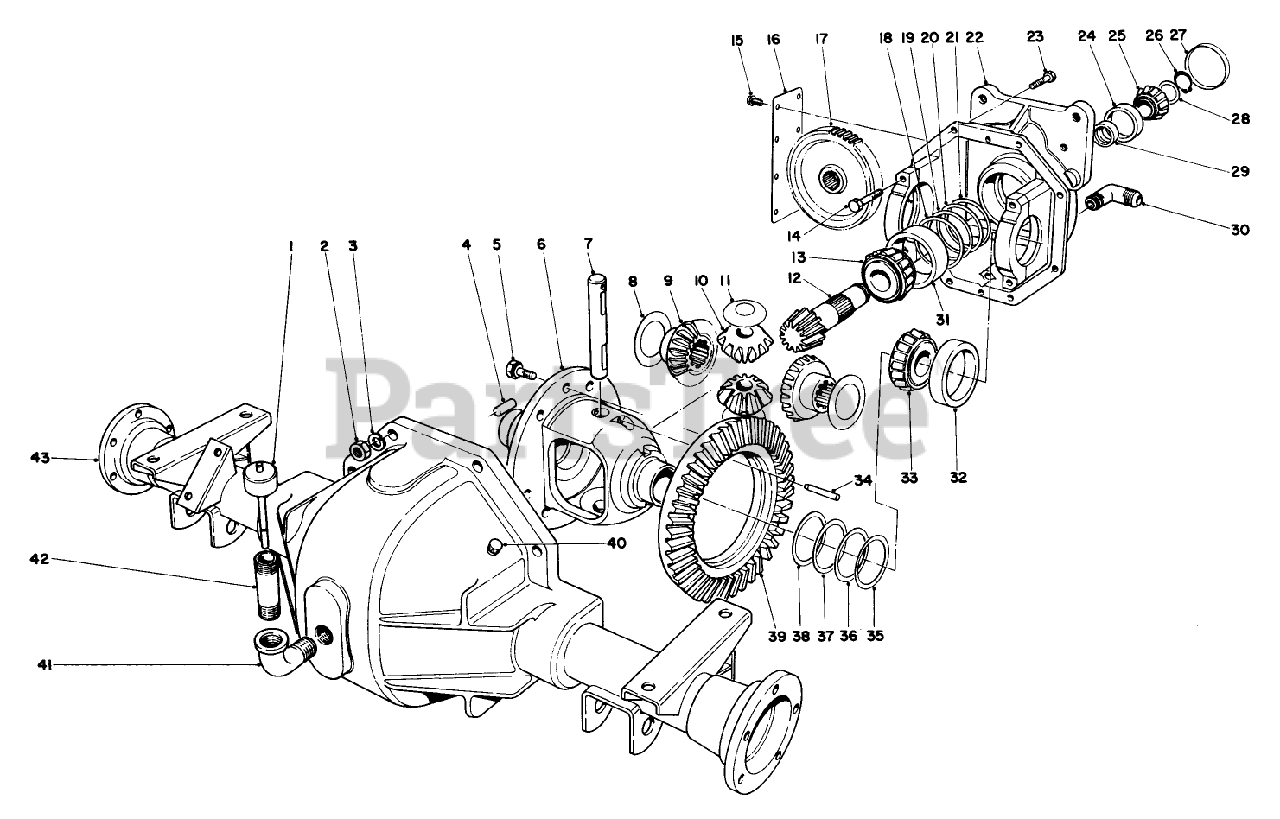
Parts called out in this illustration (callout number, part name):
1	DIPSTICK
2	NUT-HEX
3	WASHER-LOCK
4	PIN-DOWEL
5	SCREW-GEAR, DRIVE
6	CASE-DIFFERENTIAL
7	SHAFT-MATE, PINION
8	WASHER-THRUST
9	GEAR-DIFFERENTIAL
10	PINION-DIFFERENTIAL
11	WASHER-THRUST, PINION
13	BEARING-ROLLER, CONE TAPER
14	SCREW-HH
15	SCREW
16	COVER-GEAR
17	Gear-Spur
18	SHIM-PINION (.003)
19	SHIM-PINION (.005)
20	SHIM-PINION (.010)
21	SHIM-PINION (.030)
22	Upper Housing Assembly (Incl. Ref. #14)
23	SCREW-HH
24	BEARING-CUP
25	CONE-BEARING
26	RING-SNAP
27	PLUG-CUP
28	SHIM-BEARING, FRONT
29	SPACER-BEARING
30	90 DEG FITTING
31	BEARING-TAPER, CUP
32	CUP-BEARING, ROLLER
33	BEARING-ROLLER, CONE
34	PIN-ROLL
35	SHIM-BEARING, DIFFERENTIAL (.003)
36	SHIM-BEARING, DIFFERENTIAL (.005)
37	SHIM-BEARING, DIFFERENTIAL (.010)
38	SHIM-BEARING, DIFFERENTIAL (.030)
39	Ring Gear
40	VENT TUBE ASM
41	FITTING-ELBOW-90
42	PIPE NIPPLE
43	HSG TUBE & PAD LWR B
